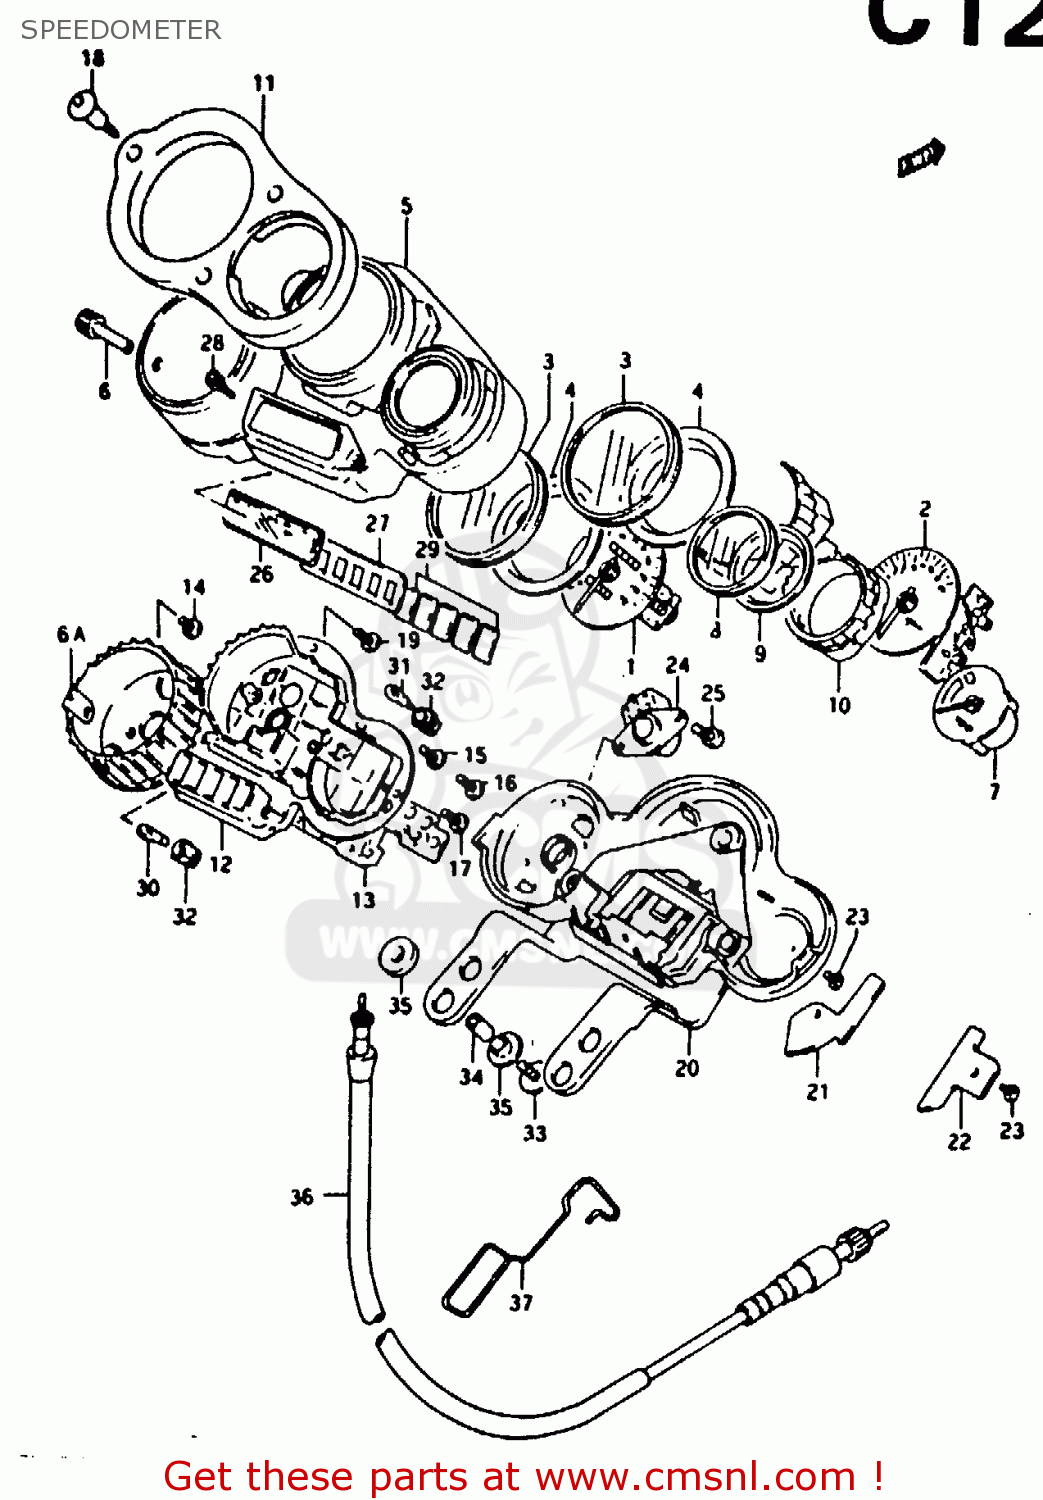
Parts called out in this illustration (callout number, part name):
1	SPEEDOMETER (KILO)
2	TACHOMETER
3	GLASS
4	PLATE,SPEEDOMETER
5	CASE,SPEEDOMETER
6	KNOB,TRIP
6A	COVER,SPEEDOMETER KNOB
7	METER,TEMP
8	GLASS,TEMPERATURE METER
9	PLATE,TEMPERATURE METER
10	CASE,TEMPERATURE METER
11	COVER, SPEEDOMETER
12	CASE,METER
13	PLATE,PRINTED
14	SCREW
15	SCREW
16	SCREW
17	SCREW
18	BOLT,COVER
19	SCREW,METER
20	COVER,LWR
21	PLATE,SPEEDOMETER
22	PLATE,TEMP METER
23	SCREW
24	BOX,METER GEAR
25	SCREW, 4X10
26	GLASS, PILOT BOX
27	GASKET
28	BOLT
29	LENS SET
30	BULB(12V3W,WB371,T7)
31	BULB(12V1.7W,WB372,T7)
32	SOCKET
33	BOLT(6X25)
34	SPACER (6.1X8X15)
35	CUSHION
36	CABLE ASSY,SPEEDOMETER
37	GUIDE,SPEEDOMETER CABLE
